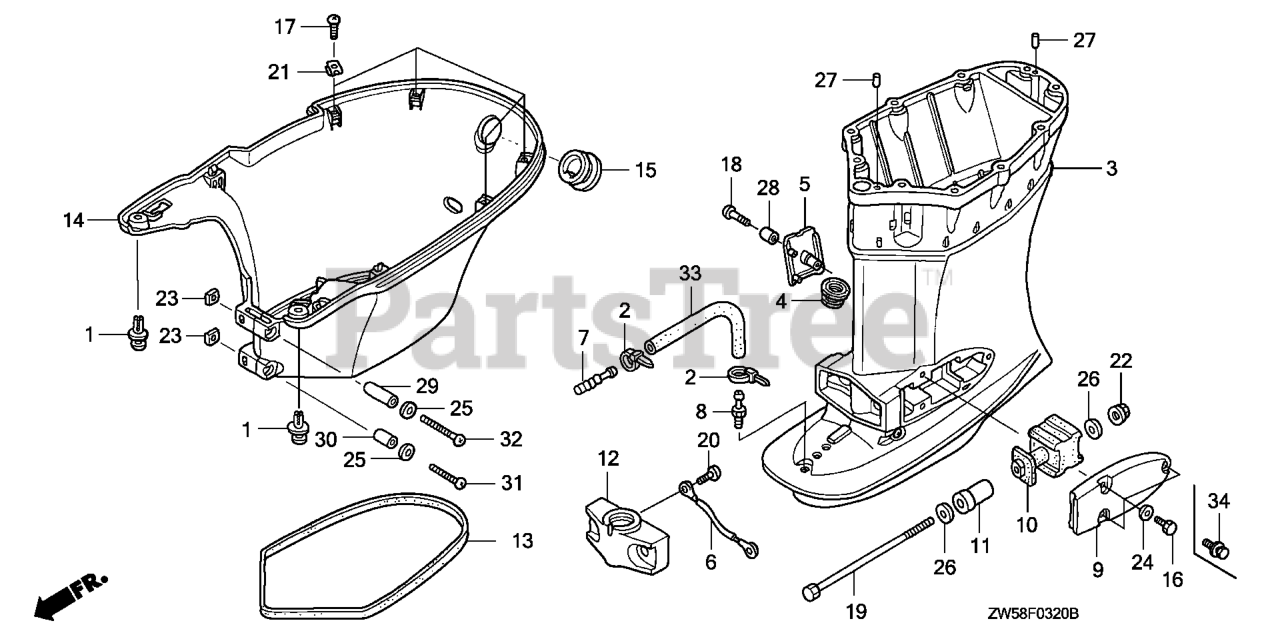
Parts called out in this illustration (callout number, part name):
1	CLIP, FUEL PIPE (BLACK)
2	BAND, WIRE
3	CASE, EXTENSION *NH282MU* (L) (OYSTER SILVER METALLIC-U)
4	RUBBER, DRAIN PLUG
5	COVER, DRAIN PLUG *NH282MU* (OYSTER SILVER METALLIC-U)
6	WIRE, LEAD (1.5X116MM)
7	END, NIPPLE
8	NIPPLE, SENSOR
9	HOUSING, MOUNTING (LOWER) *NH282MU* (OYSTER SILVER METALLIC-U)
10	RUBBER, MOUNT (LOWER)
11	COLLAR, MOUNTING (LOWER)
12	HOUSING, CENTER MOUNTING (LOWER) *NH282MU* (OYSTER SILVER METALLIC-U)
13	RUBBER, COVER (LOWER)
13	SEAL B, COVER (LOWER)
14	COVER (LOWER) *NH282MU* (OYSTER SILVER METALLIC-U)
15	GROMMET, COVER (LOWER)
16	BOLT, HEX. (8X30)
17	SCREW, SPECIAL (6X14)
18	SCREW, SPECIAL (6X35)
19	BOLT, HEX. (12X232)
20	SCREW, PAN (6X8)
22	NUT, FLANGE (12MM)
23	NUT, PLATE (5MM)
24	WASHER, PLAIN (8MM)
25	WASHER, PLAIN (5MM)
26	WASHER, PLAIN (12MM)
27	PIN, DOWEL (6X10)
28	COLLAR, DISTANCE (6X10.5X25)
29	COLLAR, DISTANCE (5X7X38)
30	COLLAR, DISTANCE (5X7X23)
31	SCREW, PAN (5X30)
32	SCREW, PAN (5X45)
33	BULK HOSE, VACUUM (5X3000) (5X250)
